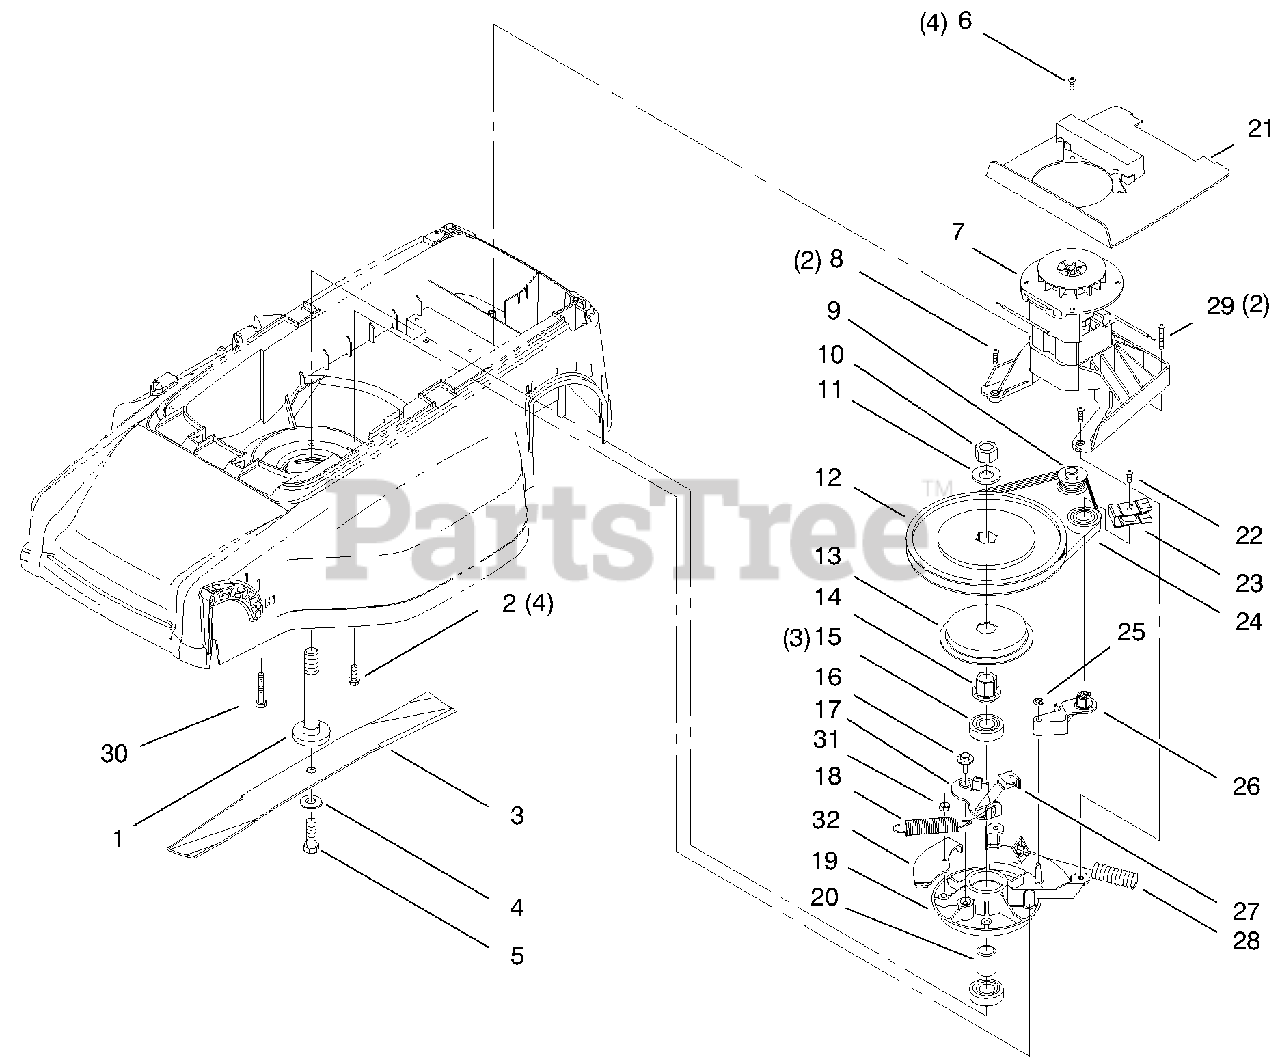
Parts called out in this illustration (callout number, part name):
1	Shaft-Spindle
2	Screw-HWH
3	Blade
4	Washer-Spring
5	Bolt-Blade
6	Screw-PH
7	ASM-Motor 120V
8	Screw-PPH
9	Pulley-Motor
10	Nut-Hex
11	Washer-Flat
12	Pulley-Driven
13	Drum-Brake
14	Hub-Pulley
15	Bearing-Ball
16	Screw-Shoulder
17	ASM-Brake Lever
18	Spring-Brake/Switch
20	Spacer-Bearing
21	ASM-Baffle
22	Screw-PH
23	Guide-Belt
25	Pushnut
27	Mount-Cable
28	Spring-Compression
29	Screw-PPH
30	Screw-HWH
31	Nut-Hex Lock
